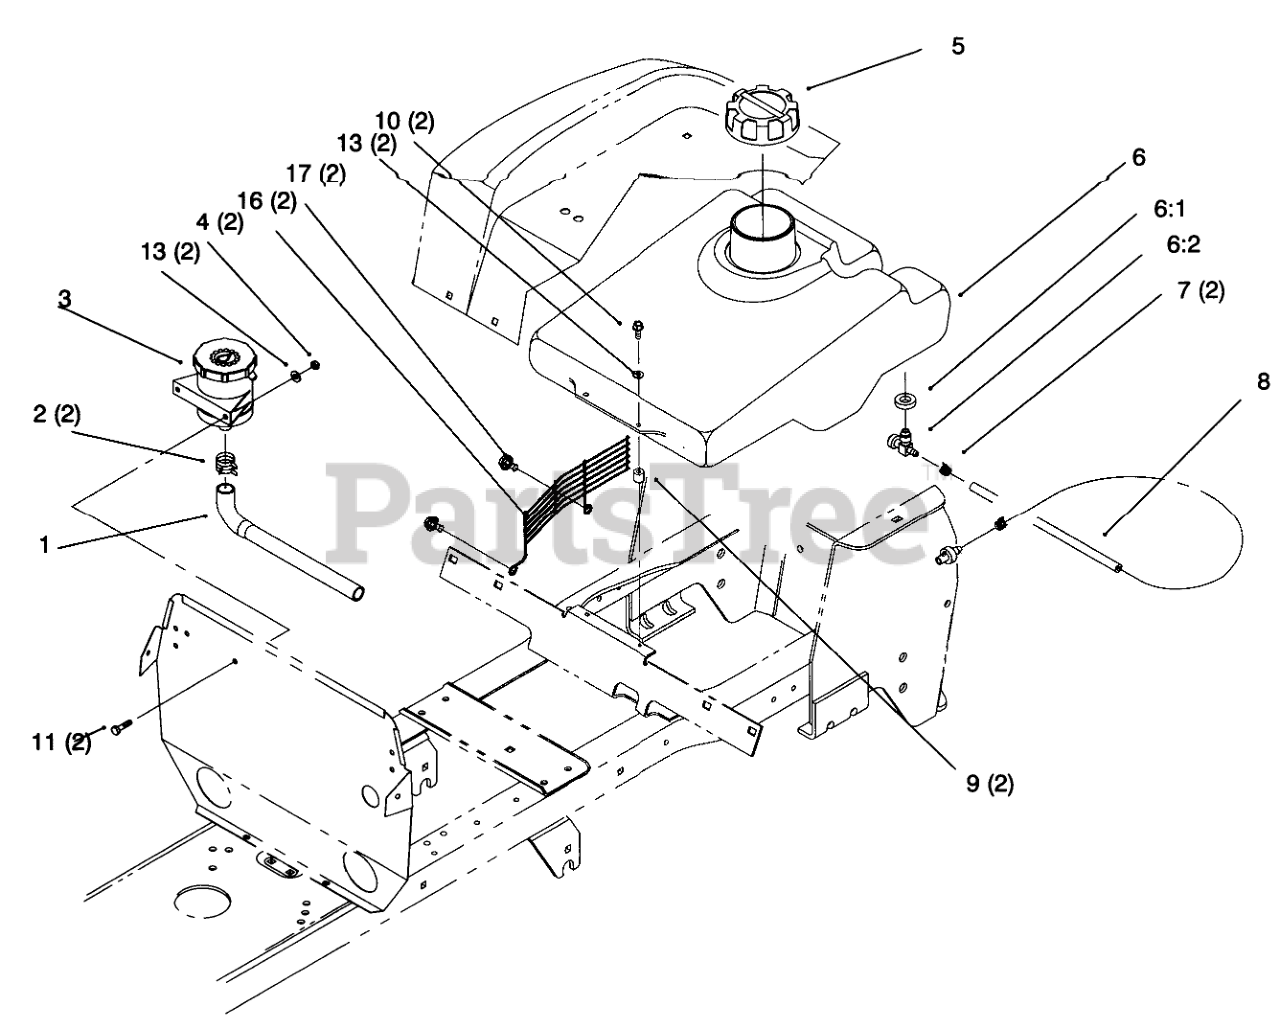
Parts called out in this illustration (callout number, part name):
1	Hose (Only On: 72043, 72063, 72103)
2	Clamp-Hose (Only On: 72043, 72063, 72103)
3	Reservoir (Only On: 72043, 72063, 72103)
4	Nut-Lock (Only On: 72043, 72063, 72103)
5	GAS CAP ASM
6	Tank-Gas
6:1	BUSHING
6:2	VALVE-FUEL
7	CLAMP-HOSE
8	Hose-Fuel Line (Only On: 72042, 72043, 72062, 72063)
8	Hose-Fuel Line (Only On: 72103)
9	Spacer-Fuel Tank (Only On: 72043, 72063, 72103)
10	Screw-HHST (Only On: 72043, 72063, 72103)
10	Screw-TAP (Only On: 72042, 72062)
11	Screw-HH (Only On: 72043, 72063, 72103)
13	Washer-Flat (Only On: 72043, 72063, 72103)
16	Guard-Fan (Only On: 72063, 72103)
17	Screw-HWHTF (Only On: 72063, 72103)
